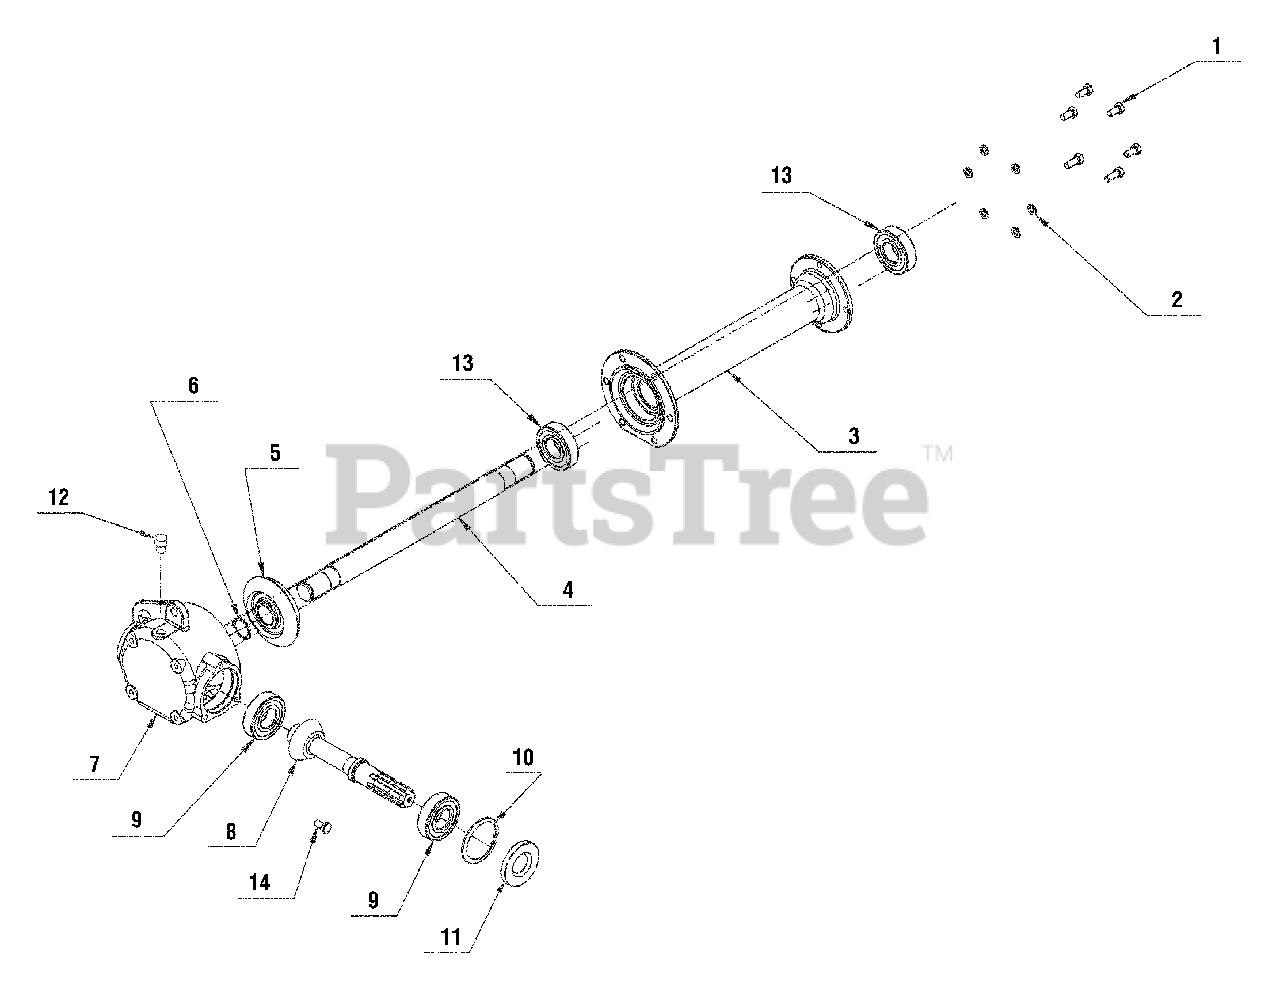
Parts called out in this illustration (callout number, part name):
3	Tube, Output Shaft
4	Shaft, Output
5	Gear, Miter
6	Snap Ring
7	Housing, Gearbox
8	Shaft, Input
9	Bearing, Gearbox
11	Spacer, 35 x 80 x 10
13	Bearing, Gearbox
